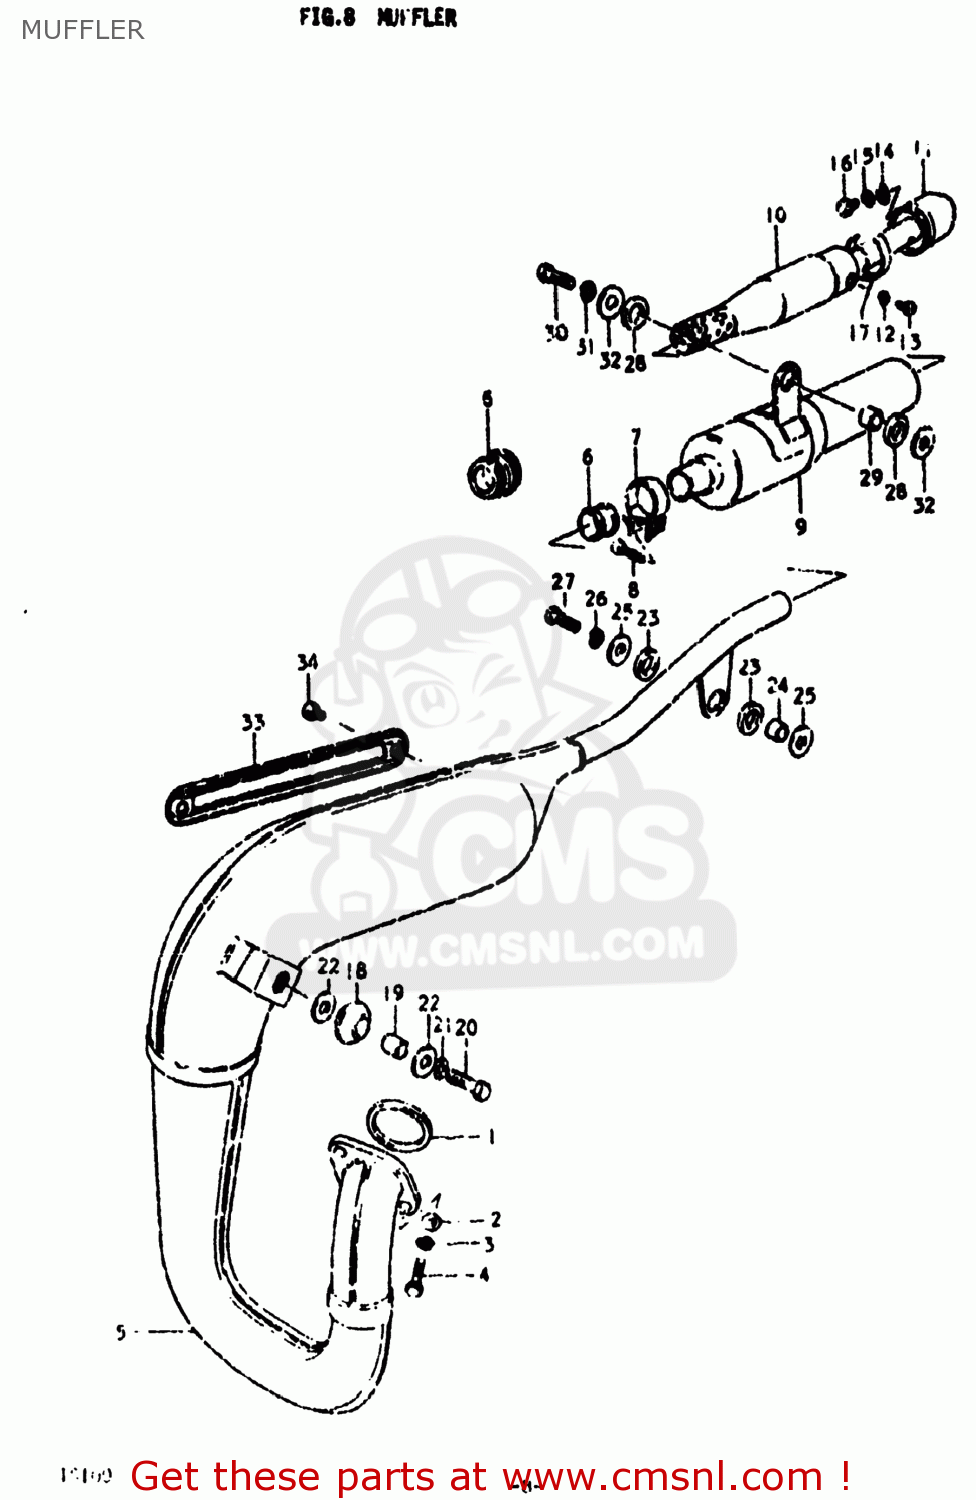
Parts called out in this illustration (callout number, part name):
1	GASKET,EXHAUST PIPE (NAS)
2	WASHER
3	LOCK WASHER
4	BOLT(6X30)
5	BODY,MUFFLER
6	CONNECTOR,MUFFLER
7	CLAMP
8	SCREW
9	MUFFLER ASSEMBLY
10	ARRESTER,SPARK
11	TUBE,MUFFLER CLEAN OUT
12	LOCK WASHER
13	SCREW
14	WASHER
15	LOCK WASHER
16	SCREW(6X8)
17	BAND,SPARK ARRESTER
18	DAMPER,MUFFLER,FR
19	SPACER (8X12X15)
20	BOLT
21	LOCK WASHER
22	WASHER (8.7X22X2)
23	CUSHION
24	SPACER (8.6X13.8X9.8)
25	WASHER
26	LOCK WASHER
27	BOLT
28	CUSHION
29	SPACER (8.6X13.8X9)
30	BOLT
31	LOCK WASHER
32	WASHER
33	COVER,MUFFLER
